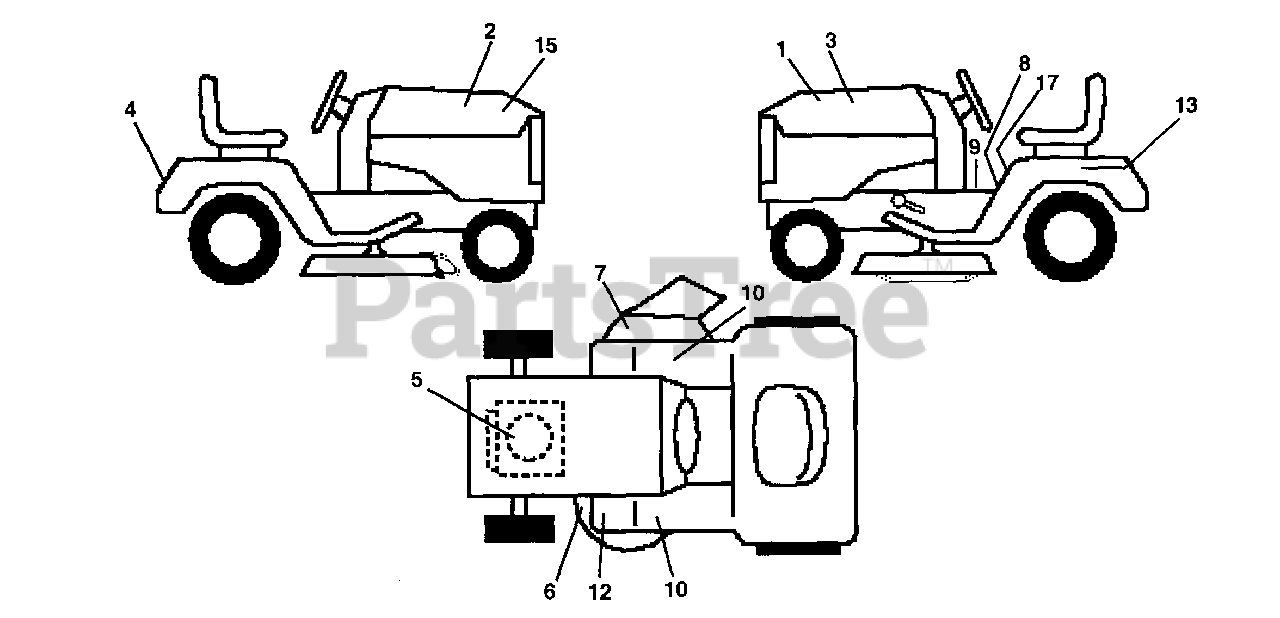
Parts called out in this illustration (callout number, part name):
1	Decal Hood Husqvarna LH
2	Decal Hood Husqvarna RH
3	Decal Panel Side LH
4	Decal Fender
5	Decal Engine 12.5 HP B&S ICQ
6	Decal, V-Belt Sch 38"/42" LT
7	Decal Warning MULT-LANGUAGE
8	Decal Dash Instructions Operating Eng/Fr
9	Decal Sdl Cold Start Hydo Eng/Fr
10	Pad Footrest Ribbed
12	Decal Clutch/brake Eng/Fr/Ger/Du
13	Decal Caution Battery Fr/Ger
15	Decal Panel Side RH Hydr.
17	Decal Caution Fender Eng/Fr
